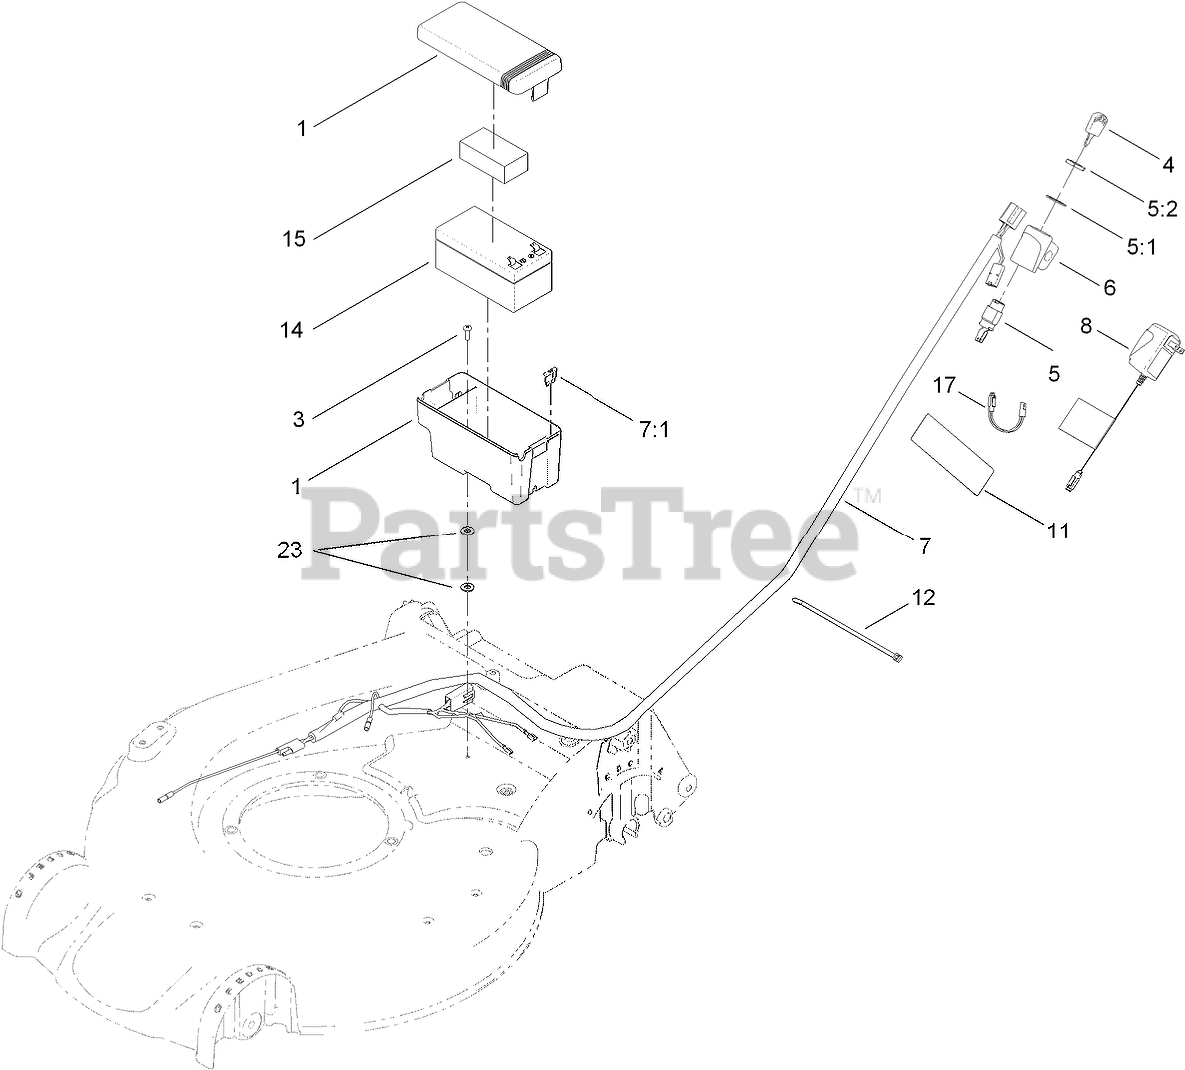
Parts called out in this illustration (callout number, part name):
1	BATTERY BOX ASM
5	STARTER SWITCH ASM
5:1	WASHER-TOOTH, INTERNAL
5:2	NUT-HH
6	MOUNT-SWITCH
7	HARNESS-WIRE
7:1	FUSE-40 AMP
8	CHARGER-EUROPEAN, 12V DC
11	DECAL-WARNING
12	TIE-CABLE
14	BATTERY-WET
15	FOAM-BATTERY, TOP
17	ADAPTER-CHARGER
23	WASHER-FLAT
